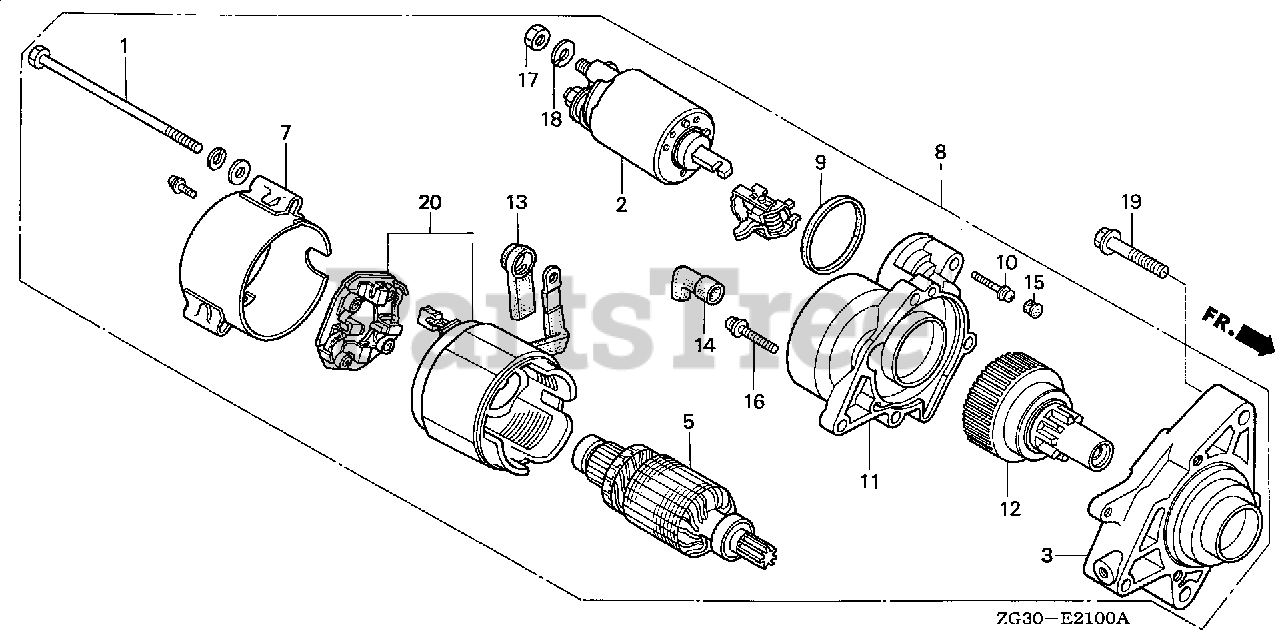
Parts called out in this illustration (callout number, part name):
1	BOLT, THROUGH
2	SWITCH ASSY., MAGNETIC (NOT AVAILABLE)
2	SWITCH ASSY., MAGNETIC
3	COVER, GEAR
5	ARMATURE (N/A: SEE ASSEMBLY)
5	ARMATURE ASSY. (N/A: SEE ASSEMBLY)
7	BRACKET, RR. UNIT
8	STARTER MOTOR ASSY.
9	RING, SQUARE (MITSUBA) (NOT AVAILABLE)
10	SCREW-WASHER (4X28) (MITSUBA)
11	CASE, FR. (NOT AVAILABLE)
11	CASE, FR.
12	GEAR ASSY. (NOT AVAILABLE)
13	COVER, TERMINAL (MITSUBA)
14	TUBE, LABYRINTH (NOT AVAILABLE)
14	TUBE, LABYRINTH
15	RUBBER, BUSH (MITSUBA)
16	SCREW-WASHER (6X30)
17	NUT, HEX. (8MM)
18	WASHER, SPRING (8MM)
19	BOLT, FLANGE (8X40)
20	STATOR SET
